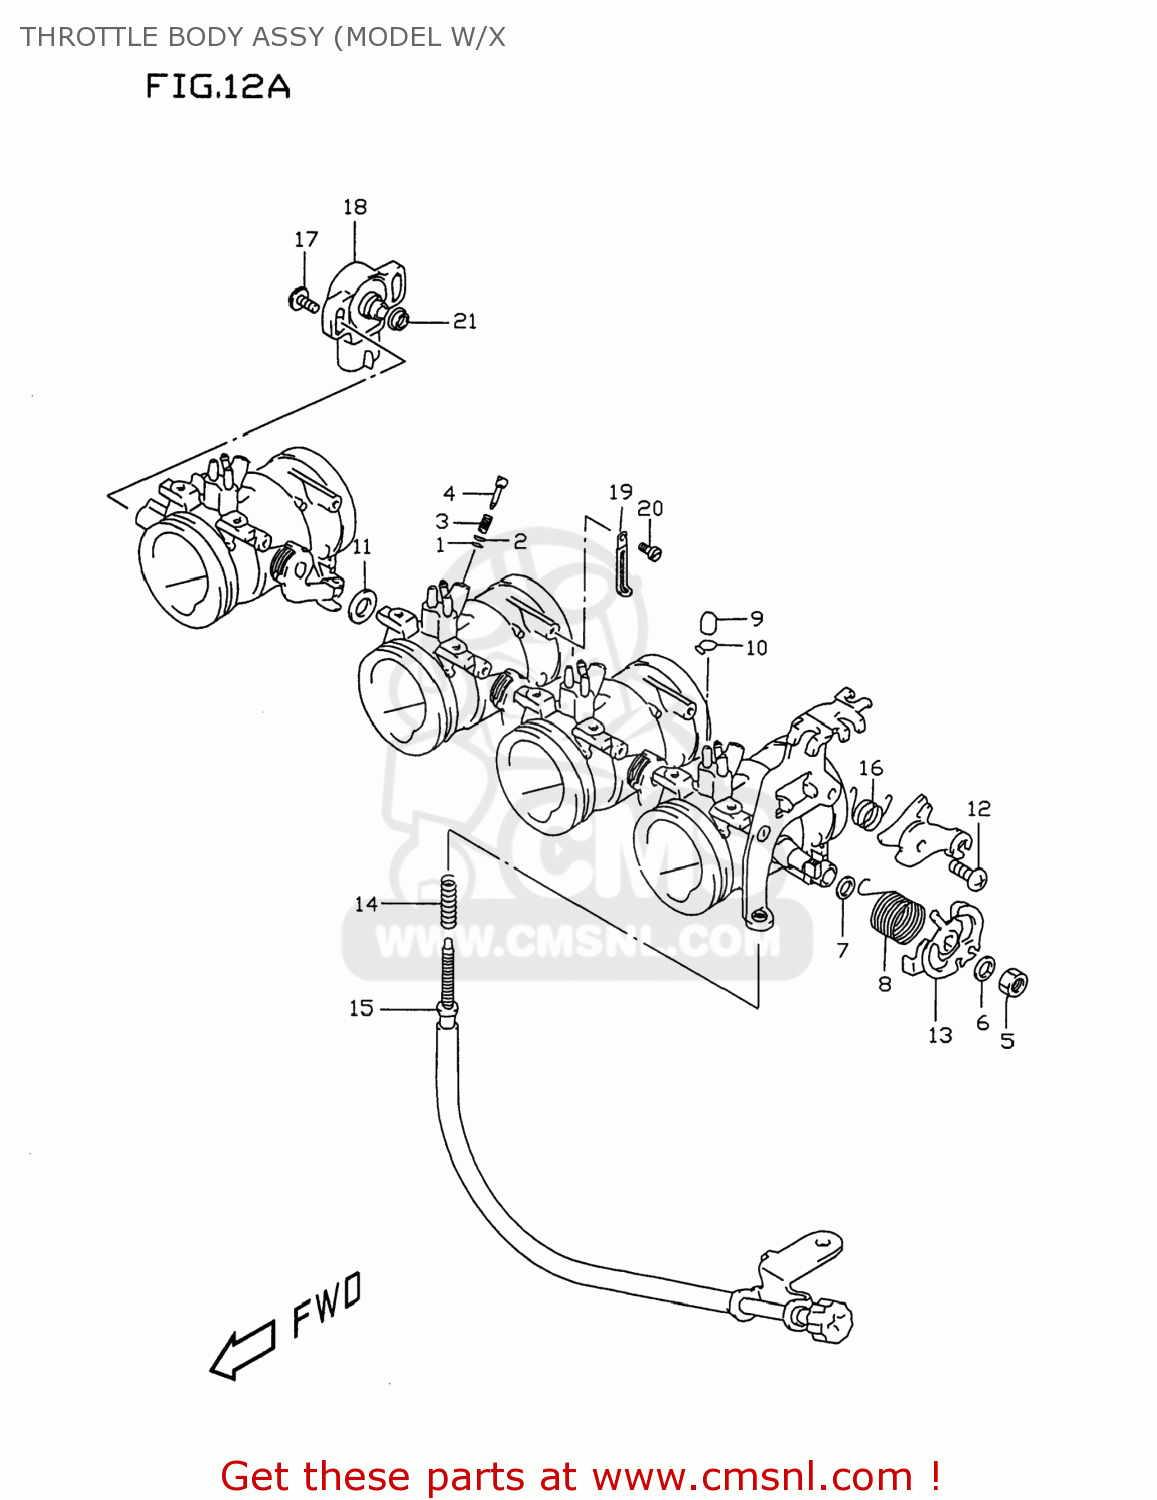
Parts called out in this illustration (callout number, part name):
1	O RING,PILOT AIR SCREW
2	WASHER
3	SPRING
4	SCREW
5	NUT
6	WASHER,LOCK
7	SEAL
8	SPRING
9	CAP
10	CLIP
11	GASKET,THROTTLE SHAFT (NAS)
12	SCREW,STARTER LEVER
13	WASHER
14	SPRING
15	ADJUSTER
16	SPRING
17	SCREW
18	SENSOR ASSY,THROTTLE
19	CLAMP(L:45)
20	BOLT
21	GASKET,THRO VALVE INSPECTION (NAS)
